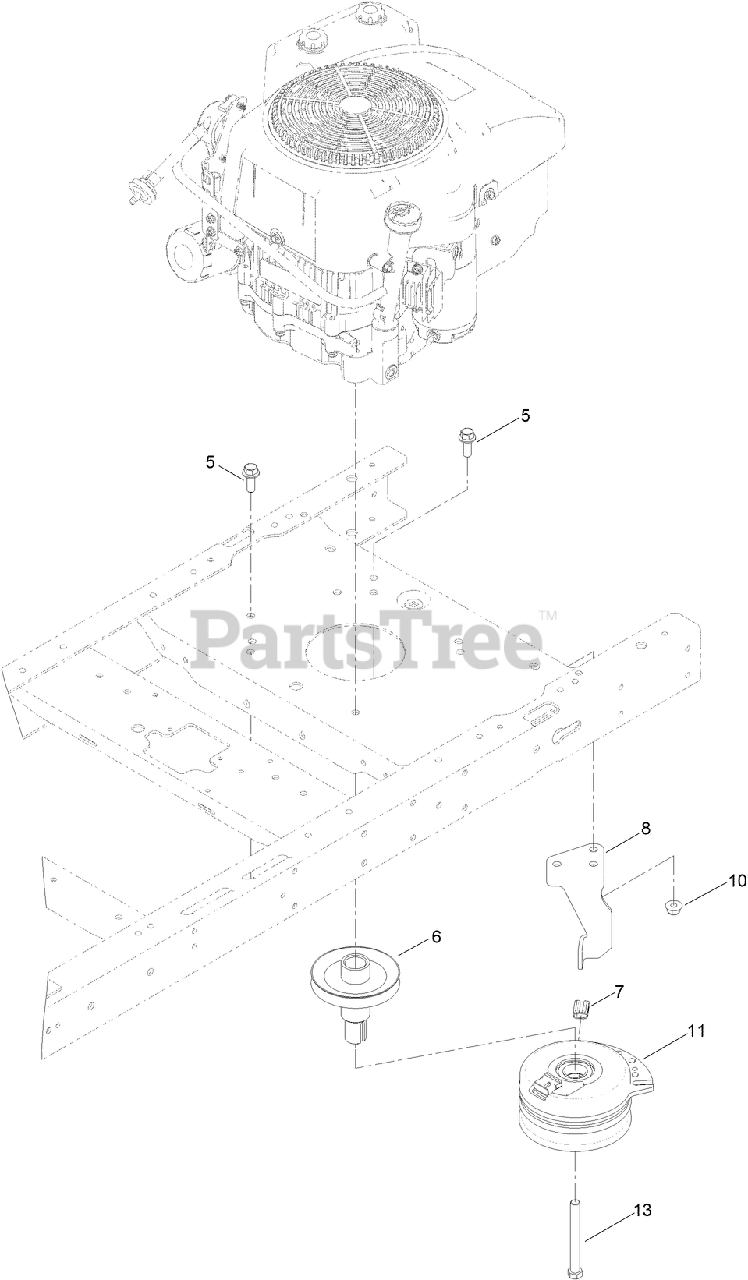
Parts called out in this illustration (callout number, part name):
5	SCREW-HHF
6	PULLEY-ENGINE
7	ISOLATOR-CLUTCH
8	STOP-CLUTCH (NARROW)
10	NUT-HF, NI
11	CLUTCH-ELECTRIC
13	SCREW-HH
